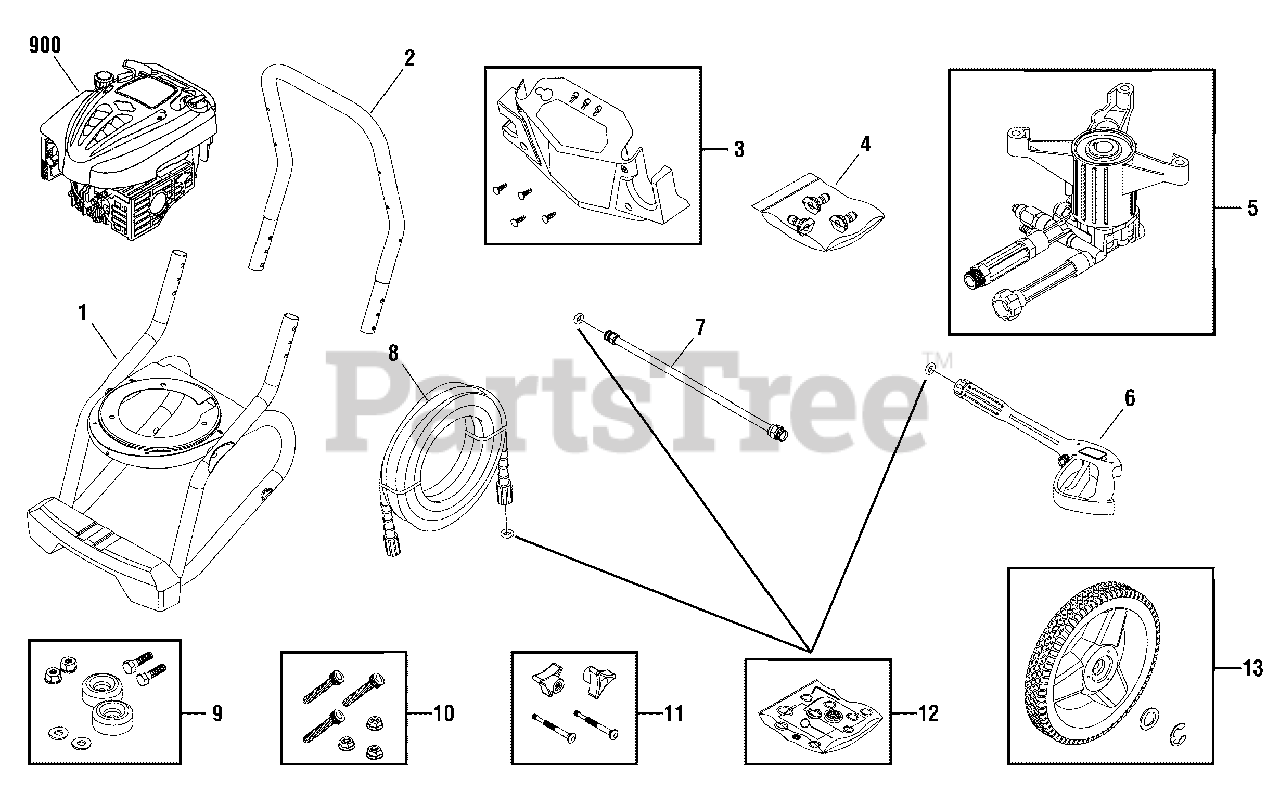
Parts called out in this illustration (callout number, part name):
4	KIT, QC Nozzles
5	PUMP
6	GUN
7	EXTENSION, QC
8	HOSE
9	MOUNT, Vibration
10	KIT, Hardware, Pump Mounting
11	KIT, Hardware, Handle
12	KIT, O-Ring
900	* ENGINE
